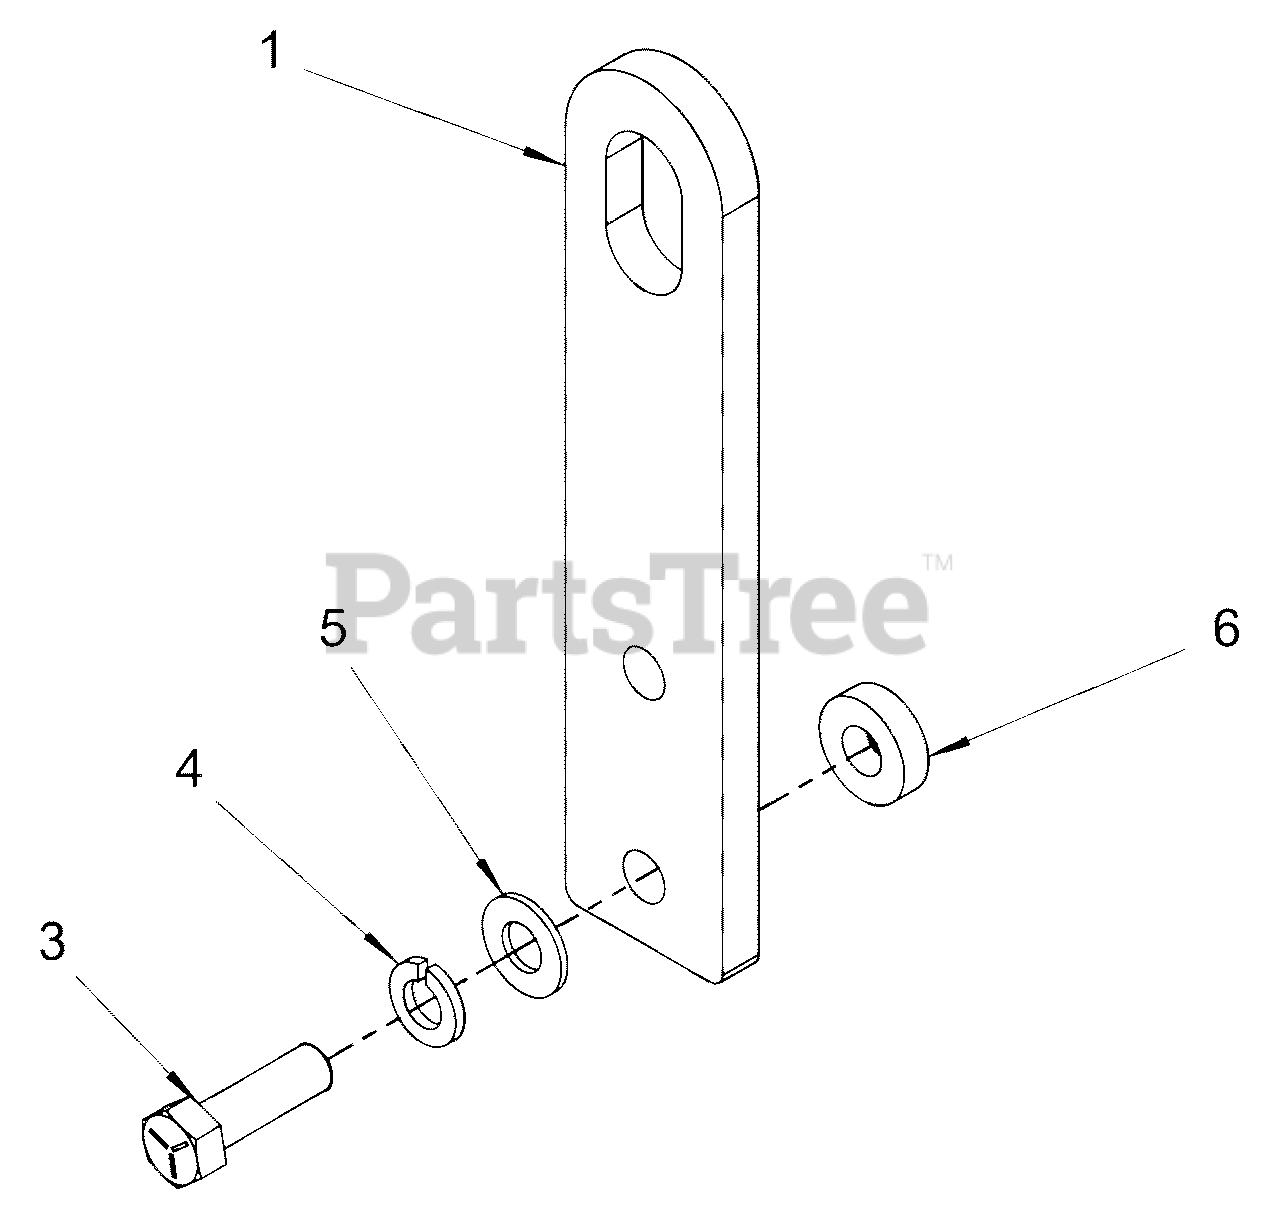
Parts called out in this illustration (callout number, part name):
1	LIFTING EYE
3	BOLT
4	WASHER, LOCK
5	WASHER, FLAT
6	WASHER
